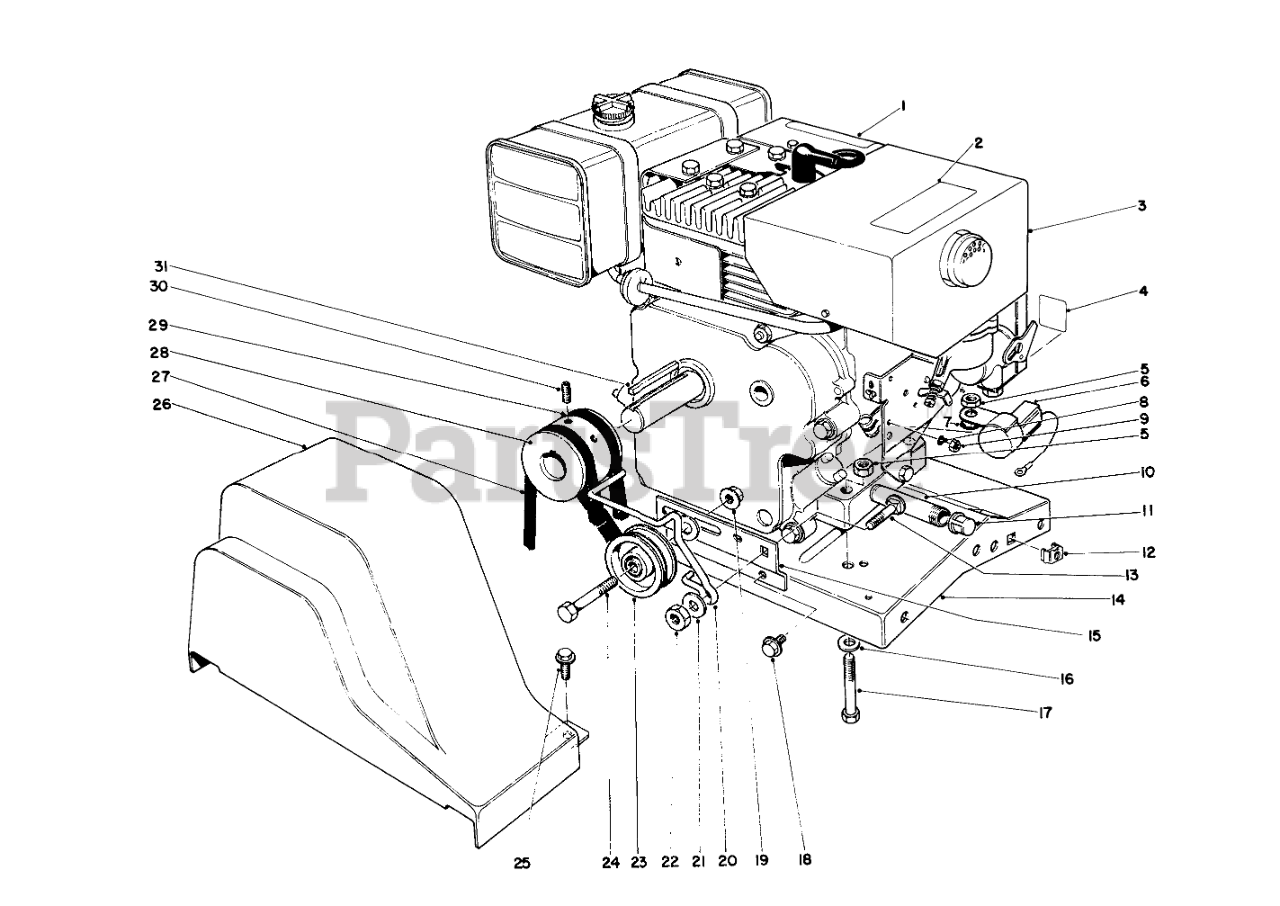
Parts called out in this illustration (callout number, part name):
1	Decal-Hazard
2	Decal Hot Surface Warning
3	Engine
4	CHOKE DECAL
5	NUT-LOCK, NI
6	INTERLOCK MODULE
7	WASHER-LOCK, INTERNAL
8	WASHER-LOCK/INT
9	NUT-LOCK
10	NIPPLE-PIPE
11	CAP-PIPE
12	Retained Nut
13	SCREW-CARR
14	Base-Engine
15	BELT IDLER BRKT
16	WASHER-PLAIN
17	SCREW-HH
18	SCREW-HHFTF
19	NUT-HHF, WHIZ
20	BELT GUIDE
21	WASHER-FLAT
22	NUT-HEX
23	PULLEY B
24	SCREW-HH
25	SCREW-HWH
26	BELT GUARD
27	V-BELT
28	ENGINE PULLEY
29	V-BELT
30	Screw-Set
